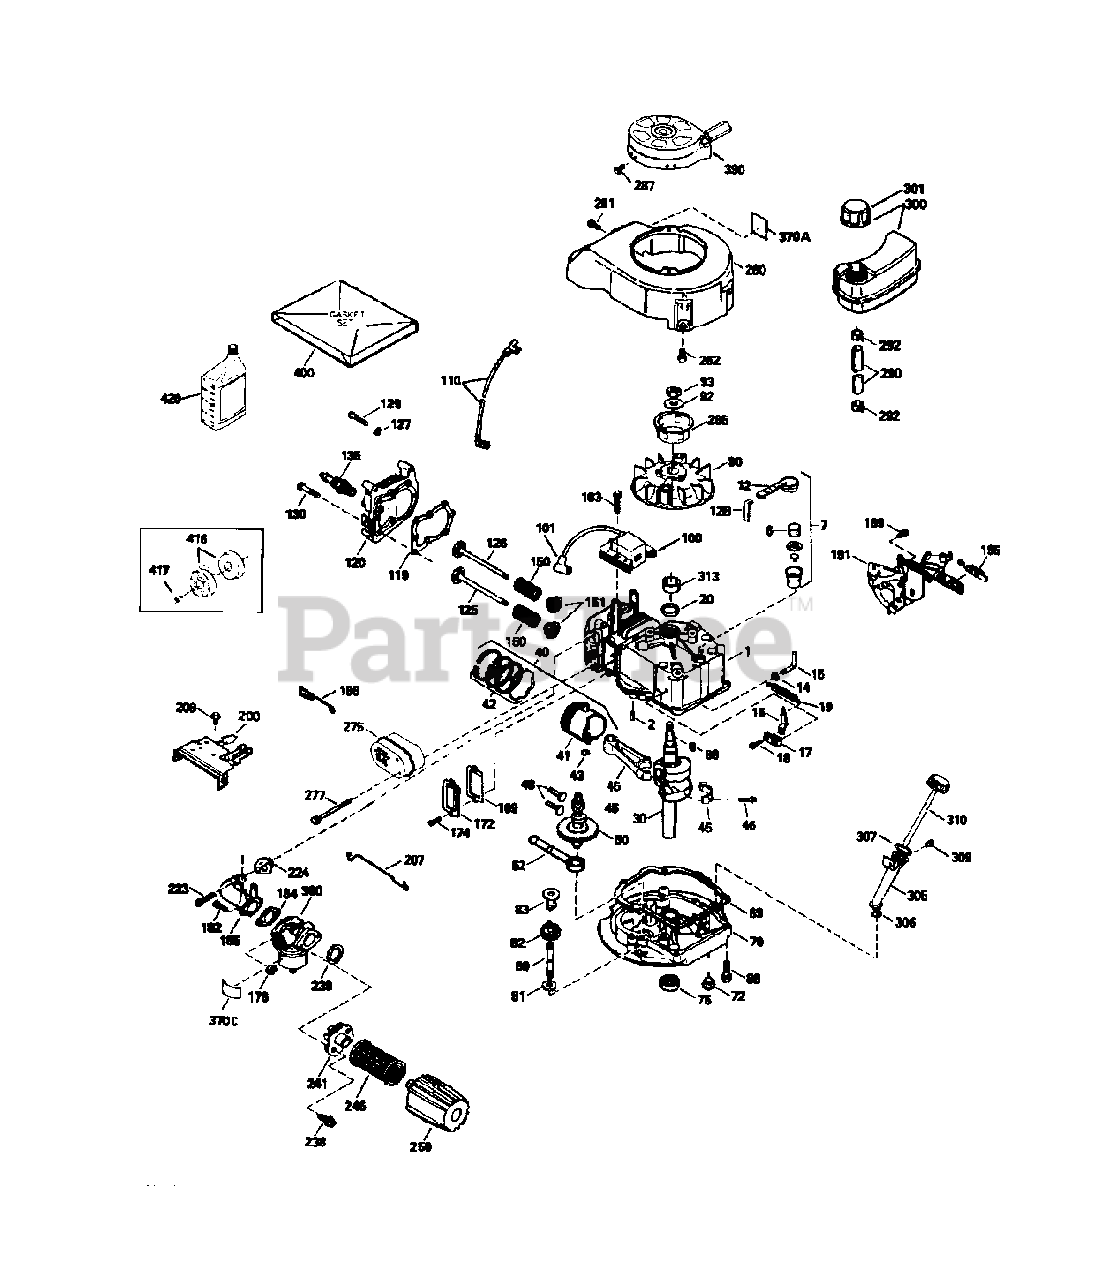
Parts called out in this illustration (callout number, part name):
1	Cylinder (Incl. 2, 7, 20 & 125)
2	Dowel Pin
6	Breather Element
7	Breather Body Ass'y (Incl. 6 & 12)
12	Breather Cover & Tube (Incl. 12B)
12B	Breather Tube Elbow
15	Governor Rod
16	Governor Lever
17	Governor Lever Clamp
19	Extension Spring
20	Oil Seal
30	Crankshaft
40	Piston, Pin & Ring Set (Std.)
40	Piston, Pin & Ring Set (.010" OS)
40	Piston, Pin & Ring Set (.020" OS)
41	Piston & Pin Ass'y. (Std.)(Incl. 43)
41	Piston & Pin Ass'y (.010" OS)(Incl. 43)
41	Piston & Pin Ass'y (.020" OS)(Incl. 43)
42	Ring Set (Std.)
42	Ring Set (.010" OS)
42	Ring Set (.020" OS)
43	Piston Pin Retaining Ring
45	Connecting Rod (Incl. 46)
46	Connecting Rod Bolt
48	Valve Lifter
50	Camshaft (MCR)
52	Oil Pump Ass'y.
69	Mounting Flange Gasket
70	Mounting Flange (Incl. 72 thru 83)
72	Oil Drain Plug
75	Oil Seal
80	Governor Shaft
82	Governor Gear Ass'y (Incl. 81)
83	Governor Spool
89	Flywheel Key
90	Flywheel
92	Belleville Washer
93	Flywheel Nut
100	Solid State Ignition
101	Spark Plug Cover
103	Screw, Torx T-15
110	Ground Wire
119	Cylinder Head Gasket
120	Cylinder Head
125	Exhaust Valve (Std.)(Incl. 151)
125	Exhaust Valve (1/32" OS)(Incl. 151)
126	Intake Valve (Std.)(Incl. 151)
126	Intake Valve (1/32" OS)(Incl. 151)
135	Resistor Spark Plug (RJ19LM)
150	Valve Spring
151	Valve Spring Cap
169	Valve Cover Gasket
172	Valve Cover
178	Nut & Lock Washer
182	Screw
184	Carburetor To Intake Pipe Gasket
185	Intake Pipe (Incl. 224)
186	Governor Link
191	S.E. Brake Bracket (Incl. 195)
195	Terminal
200	Control Bracket
207	Throttle Link
224	Intake Pipe Gasket
239	Air Cleaner Gasket
241	Air Cleaner Collar
245	Air Cleaner Filter
250	Air Cleaner Cover
260	Blower Housing
275	Muffler (Incl. 277)
285	Starter Cup
290	Fuel Line
292	Fuel Line Clamp
300	Fuel Tank (Incl. 292 & 301)
301	Fuel Cap
305	Oil Fill Tube
306	"O"-Ring
307	"O"-Ring
310	Dipstick
370A	Lubrication Decal
370C	Primer Decal
380	Carburetor (Incl. 184)
390	Rewind Starter (NOTE:This engine could have been built with 590637 starter. Refer to the design of the air intake louvers for part Identification. Individual starter parts do not interchange.)
400	Gasket Set (Incl. Items Marked PK in Notes) Incl. part #'s: 26756 (1), 27234A (1), 33735 (1), 34265(1), 34338 (1), 34690A (1), 35261 (1), 36477 (1)
416	Spark Arrestor Kit (Incl. 417)(Optional)
417	Screw (Optional)
420	SAE 30 4-Cycle Engine Oil (Quart)
